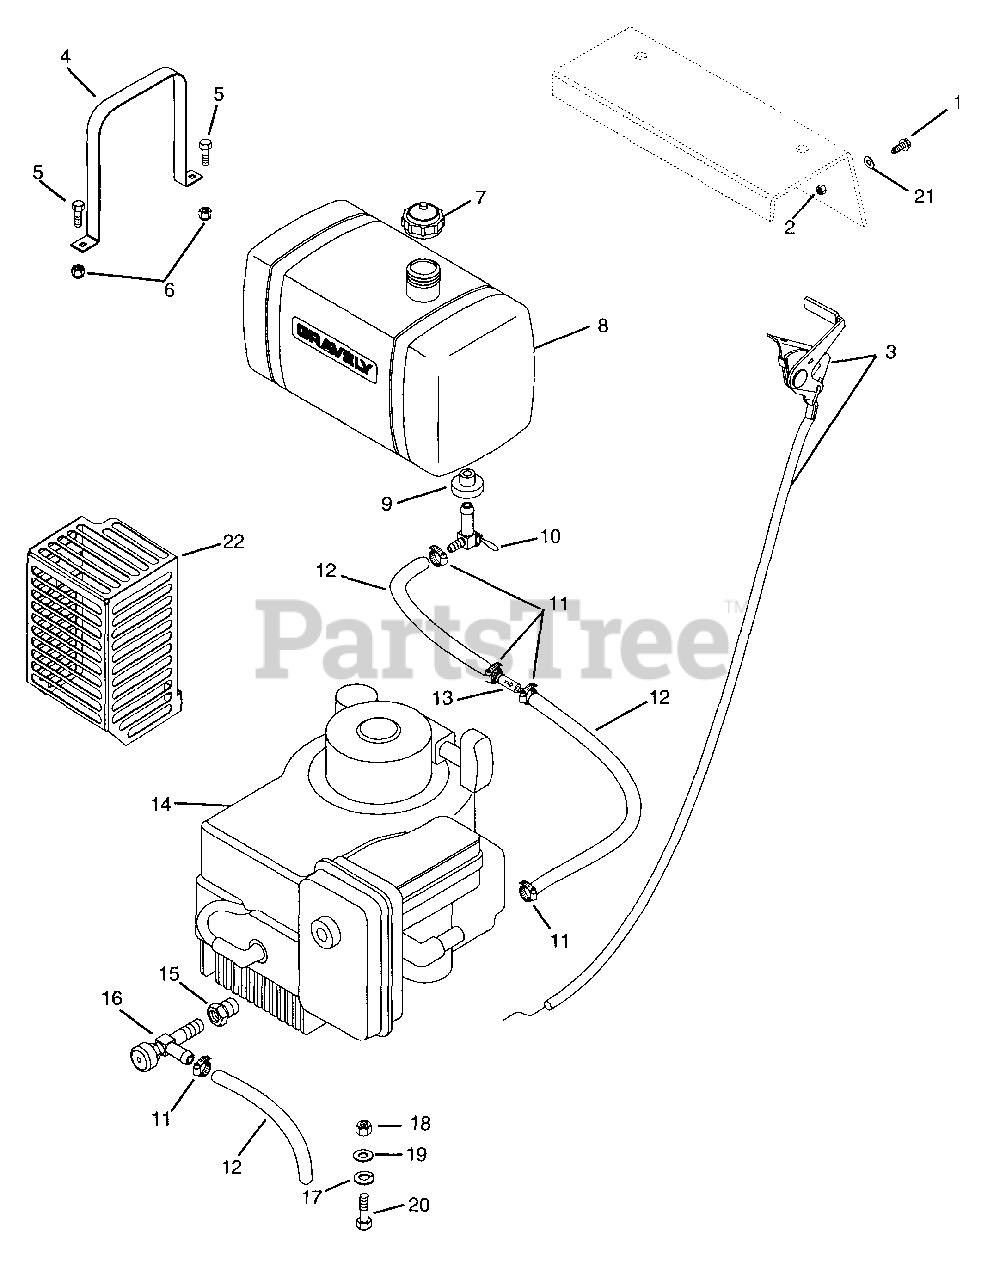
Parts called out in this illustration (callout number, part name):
1	Screw-Machine Hex Washer Head 10-24 x .50
2	Nut-Locking-Nylon 10-24 w/Insert
3	Cable-Throttle
4	Tank Strap for 4.5 G Fuel Tank
5	Bolt-Hex .25-20 x .75 Grade 5
6	Nut-Locking-Center .25-20
7	Cap-Fuel Tank
8	Fuel Tank 4.5 Gallon
9	Bushing-Flange .375 x 1.06 x .625
10	Valve-Ball Shut-Off
11	Hose Clamp
12	Gas Line-Bulk
13	Filter-Fuel
14	Engine-Kawasaki 12.5
14	Engine-14 HP Kawasaki
14	Engine 12.5 HP Tecumseh Recoil
15	Adapter-Oil Drain
16	Cock-Oil Drain
17	Washer-Lock .313 x .078
18	Nut-Locking-Center .31-18
19	Washer-Flat-Steel .344 x .688 x .065
20	Bolt-Hex M8 x 1.25 x 30 Grade 5
21	Washer-Flat-Steel .219 x .50 x .049
22	Muffler Guard (309)
